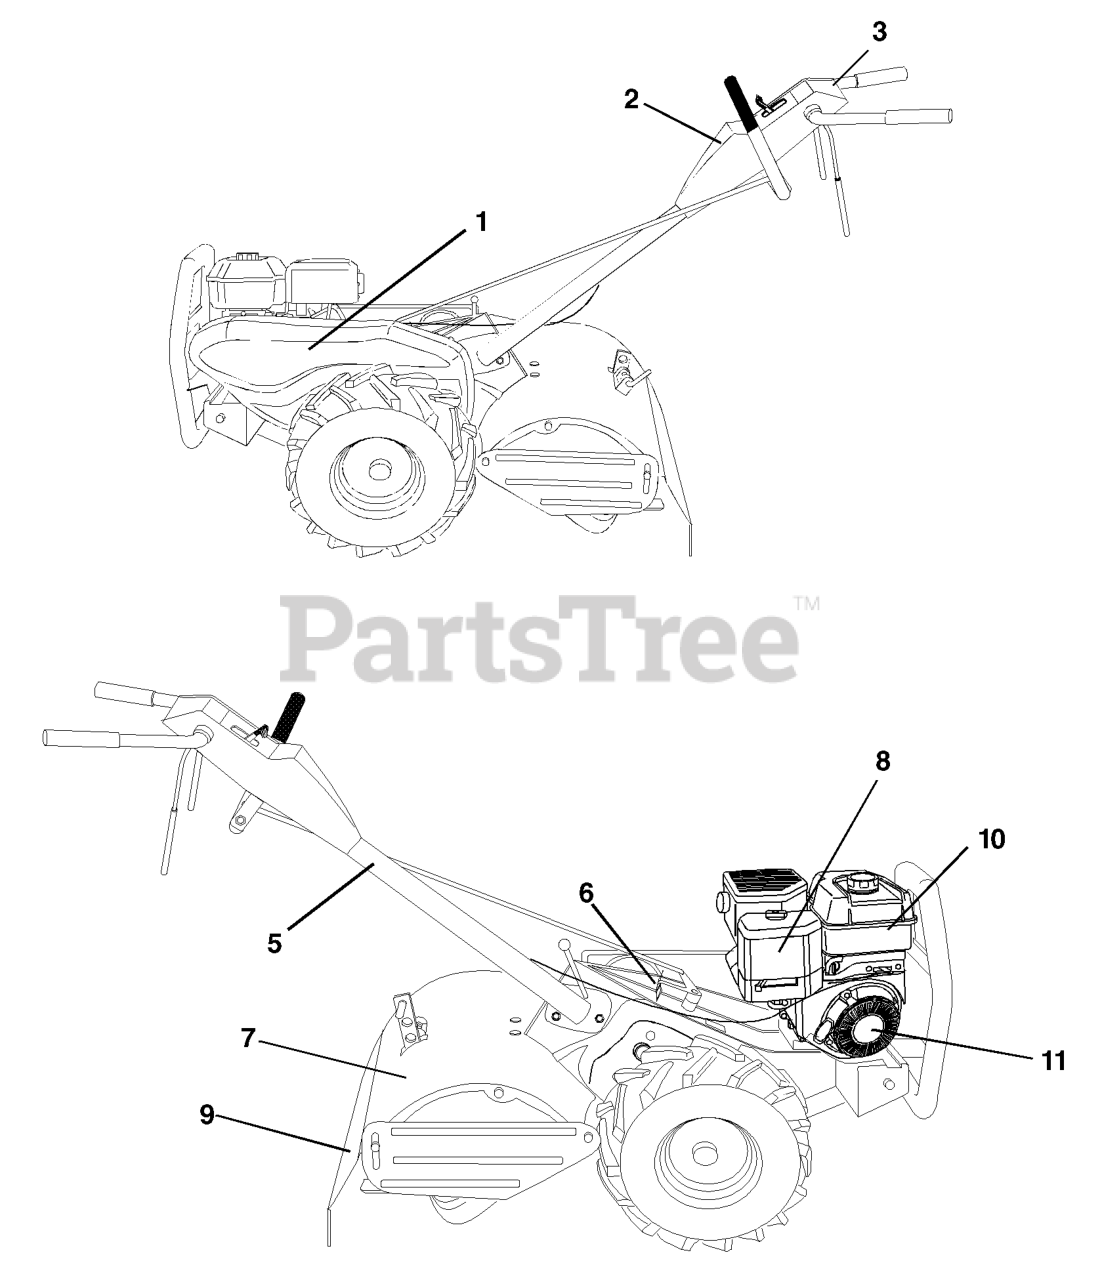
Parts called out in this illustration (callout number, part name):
1	DECAL, BOLT GUARD
2	DECAL, CTRL PANEL
3	DECAL, 650CRT
5	DECAL TI (2 2)
6	DECAL.SHIFT.INDICATOR.TILLER
7	DECAL -CAUTION
8	DECAL, ENG. B&S 6.5HP
9	DECAL TI
10	DECAL, ENG. INTEK
11	DECAL.REWIND
